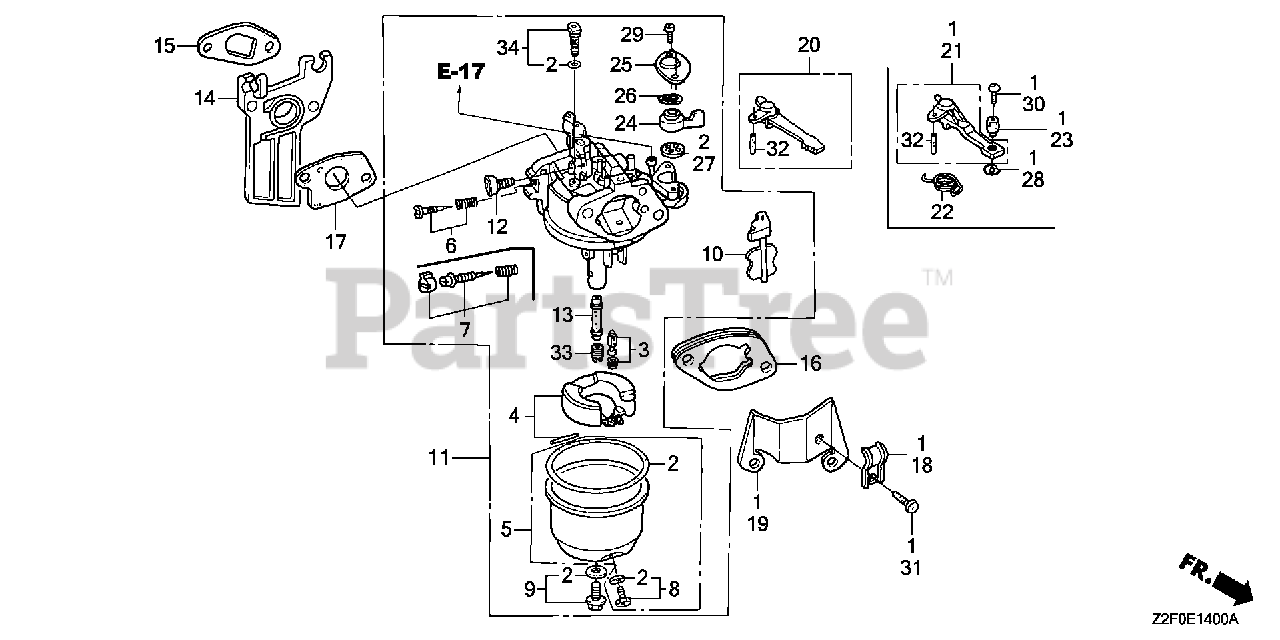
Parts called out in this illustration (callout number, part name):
1	CHOKE KIT, REMOTE CONTROL
2	GASKET SET
3	VALVE SET, FLOAT (SEAT NOT INCLUDED)
4	FLOAT SET
5	CHAMBER SET, FLOAT
6	SCREW SET, PILOT
8	SCREW SET, DRAIN
9	SCREW SET
10	CHOKE SET
11	CARBURETOR ASSY. (BE66D B)
11	CARBURETOR ASSY. (BE06H C)
12	SCREW, THROTTLE STOP
13	NOZZLE, MAIN
14	INSULATOR, CARBURETOR
15	GASKET, INSULATOR
16	SPACER, CARBURETOR
17	GASKET, CARBURETOR
18	HOLDER, CONTROL CABLE
19	STAY, CHOKE CONTROL
20	LEVER, CHOKE (STD)
21	LEVER, CHOKE (REMOTE)
22	SPRING, RETURN
23	HOLDER, CABLE
24	LEVER, PETCOCK
25	PLATE, LEVER SETTING
26	SPRING, PETCOCK LEVER
27	GASKET, PETCOCK
28	CIRCLIP (5MM)
29	SCREW, PAN (3X6)
30	SCREW, PAN (4X8)
31	SCREW, PAN (5X8)
32	PIN, SPRING (2X12)
33	JET, MAIN (#65)
33	JET, MAIN (#68)
33	JET, MAIN (#70)
34	JET SET, PILOT (#35)
